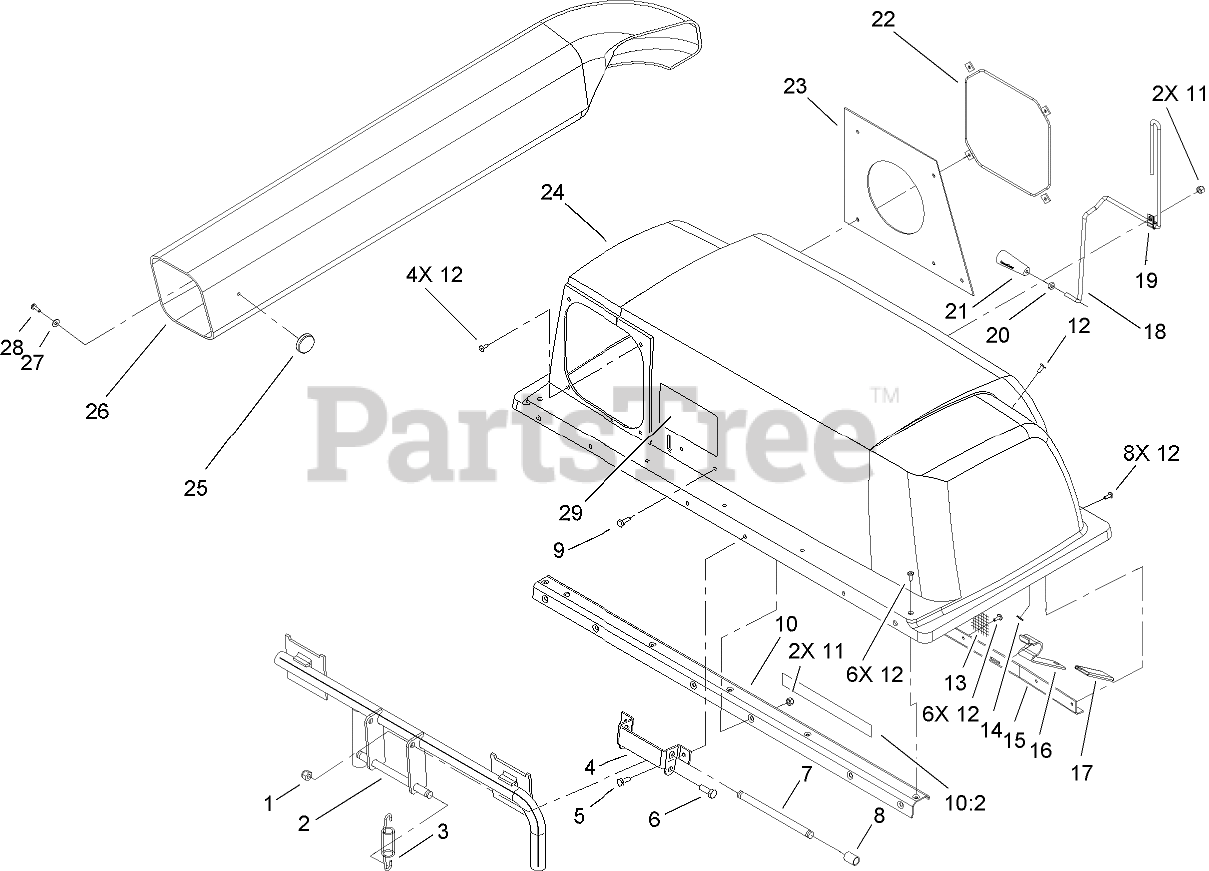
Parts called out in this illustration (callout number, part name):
1	NUT-LOCK, NI
2	FRAME ASM
3	SPRING-EXTENSION
4	Hinge-Bag, Top
5	SCREW-HH
6	SCREW-HH
7	PIN-SPRING
8	Spacer
9	SCREW-HH
10	STIFFENER ASM
10:2	DECAL-CAUTION
11	NUT-LOCK, NI
12	RIVET-BLIND
13	SCREEN-BAGGER
14	WASHER-FLAT
15	SUPPORT-SCREEN
16	LATCH-BAGGER, TOP
18	FEELER-FILL, BAG
19	CLAMP
20	NUT-JAM
21	HANDLE-TAPERED
22	CLAMP-SEAL
23	SEAL-CHUTE
24	TOP-BAGGER
26	CHUTE-DISCHARGE
27	WASHER-PLAIN
28	SCREW-PPHTF
29	DECAL
